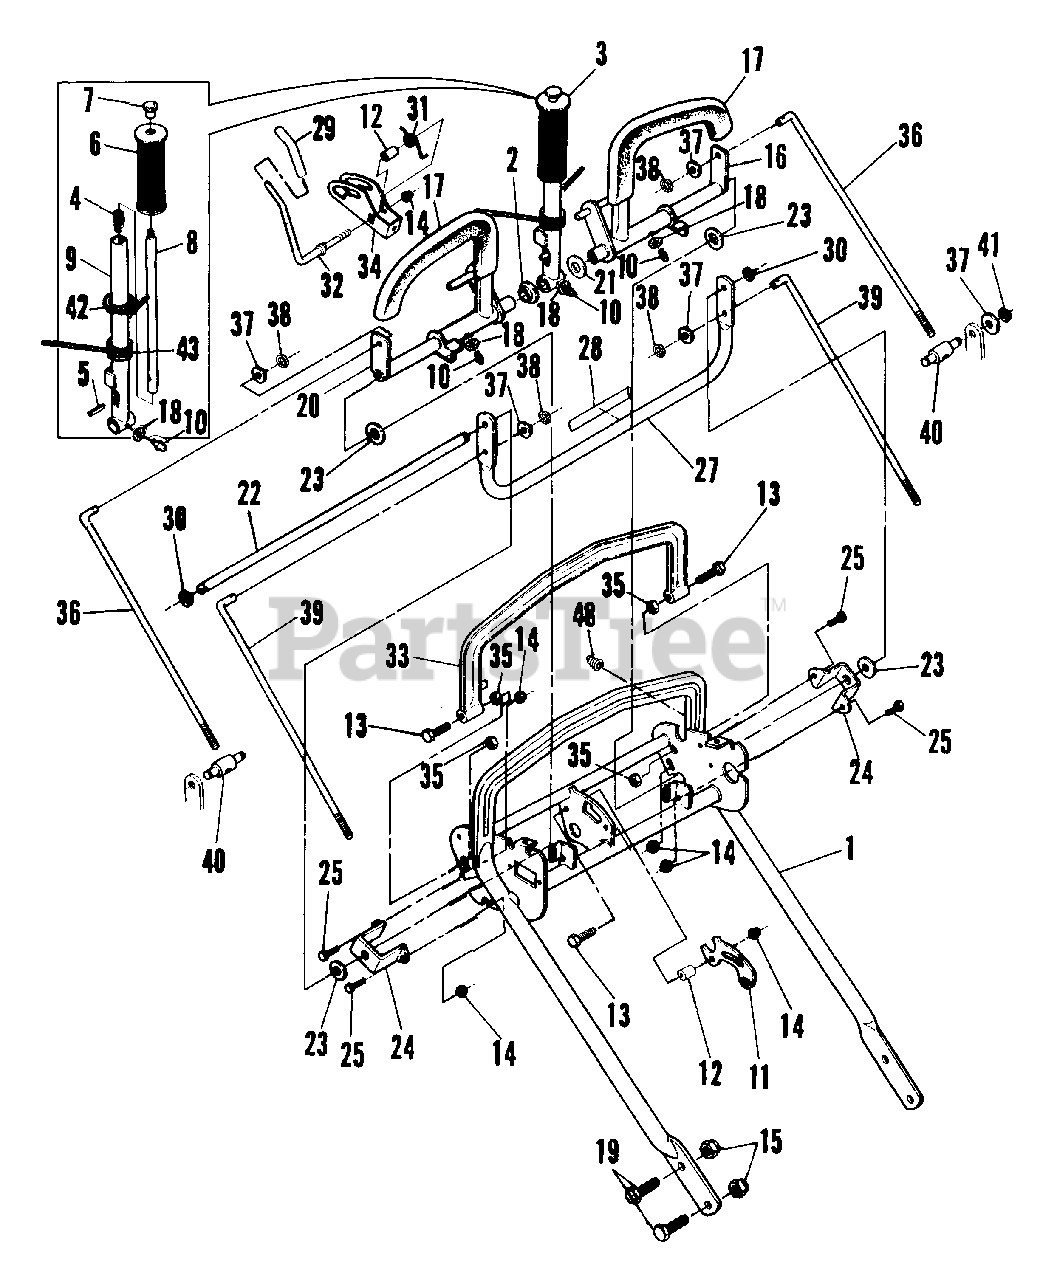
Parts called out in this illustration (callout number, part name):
1	HANDLE, Top
2	BUSHING, Brake Lever
3	LEVER, Park Assembly
5	PIN, .19 x 1.13 Gr.
6	GRIP, Park Brake
7	KNOB, Brake Release
8	RELEASE, Brake
9	LEVER, Brake
10	ZERK, 1/4"- 28, Straight
11	BRACKET, Brake Lever
12	SPACER, Park Brake
13	BOLT, 1/4"-20 x 1 1/2, Gr. 5, Hex
14	NUT, 1/4" C, Nylon Lock
15	NUT, 3/8"-16 Hex Nylon Ring
16	LEVER, Traction, Left
17	GRIP, Traction
18	WASHER, 1/4" Int. Tooth
19	SCREW, 3/8"-16 x 1" Hex Head Cap Gr. 5
20	LEVER, Traction, Right
21	BUSHING, Machinery, 3/4"
22	ROD, Pivot
23	BUSHING, Machinery, 1/2"
24	BRACKET, Pivot
25	SCREW, 1/4" C x 5/8, Gr. 5, Hex Cap
27	BAIL, Reverse
28	DECAL, Reverse Bail
29	GRIP
30	RETAINING RING
31	SPRING, Neutral
32	LEVER, Neutral
33	BAIL, OPC
34	LATCH, Neutral
35	NUT, 1/4-20 Hex Jam
36	ROD, Traction
37	FLATWASHER, 3/8"
38	RETAINER
39	ROD, Reverse Traction
40	SWIVEL, Reverse
41	RETAINING RING
42	RETAINER, 3/4
43	SPRING, Park Brake
48	SPRING
